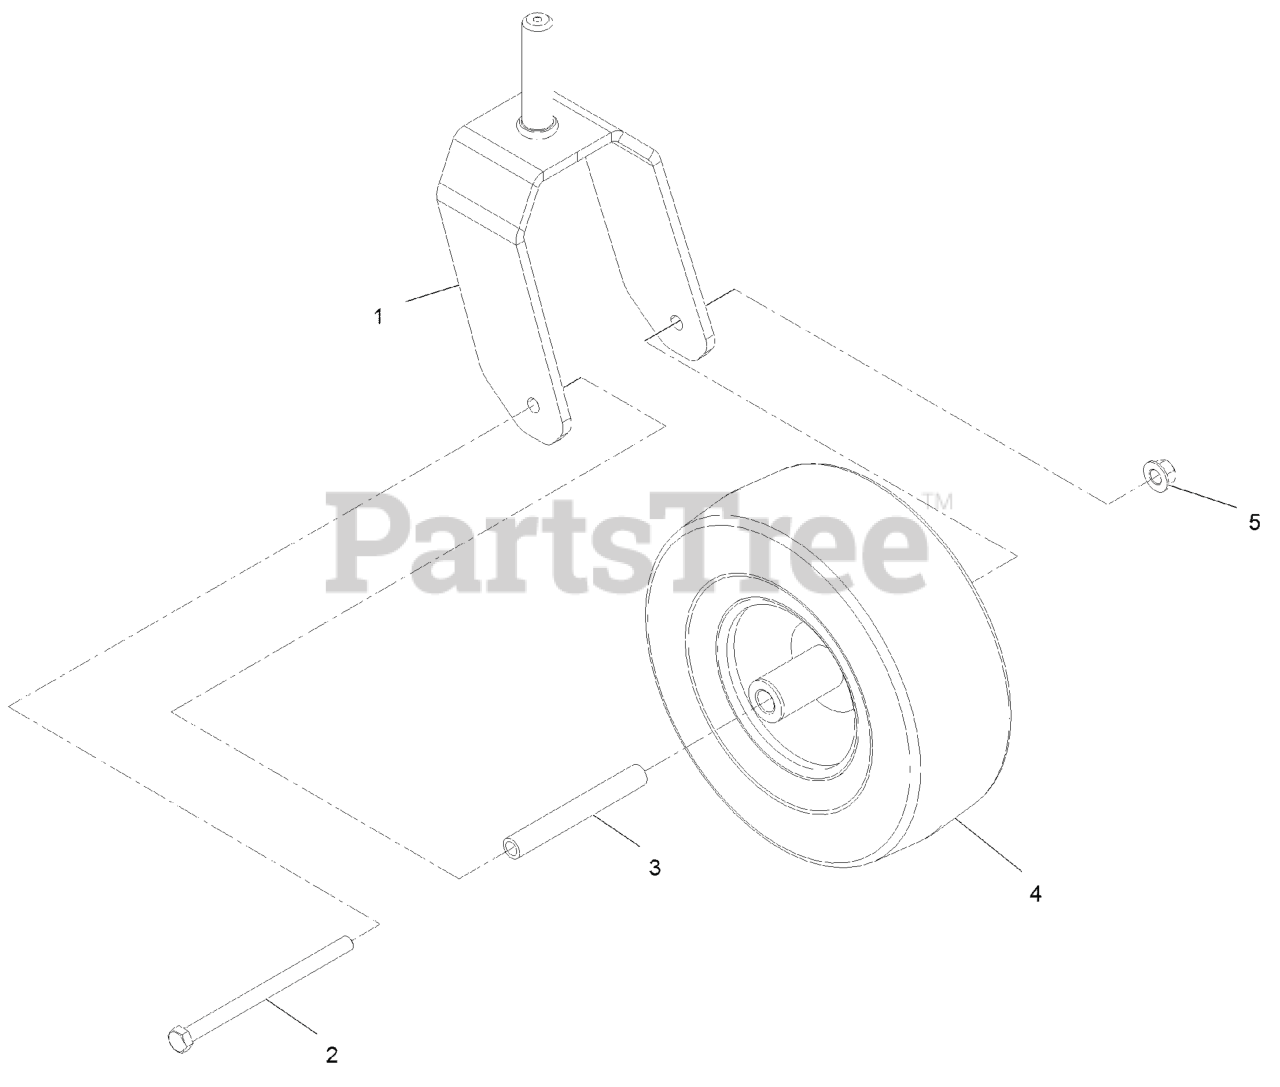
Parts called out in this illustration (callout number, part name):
1	CASTER-FORK
2	SCREW-HH
3	SPANNER
4	TIRE AND WHEEL ASM
5	Nut-Lock 1/2-13
